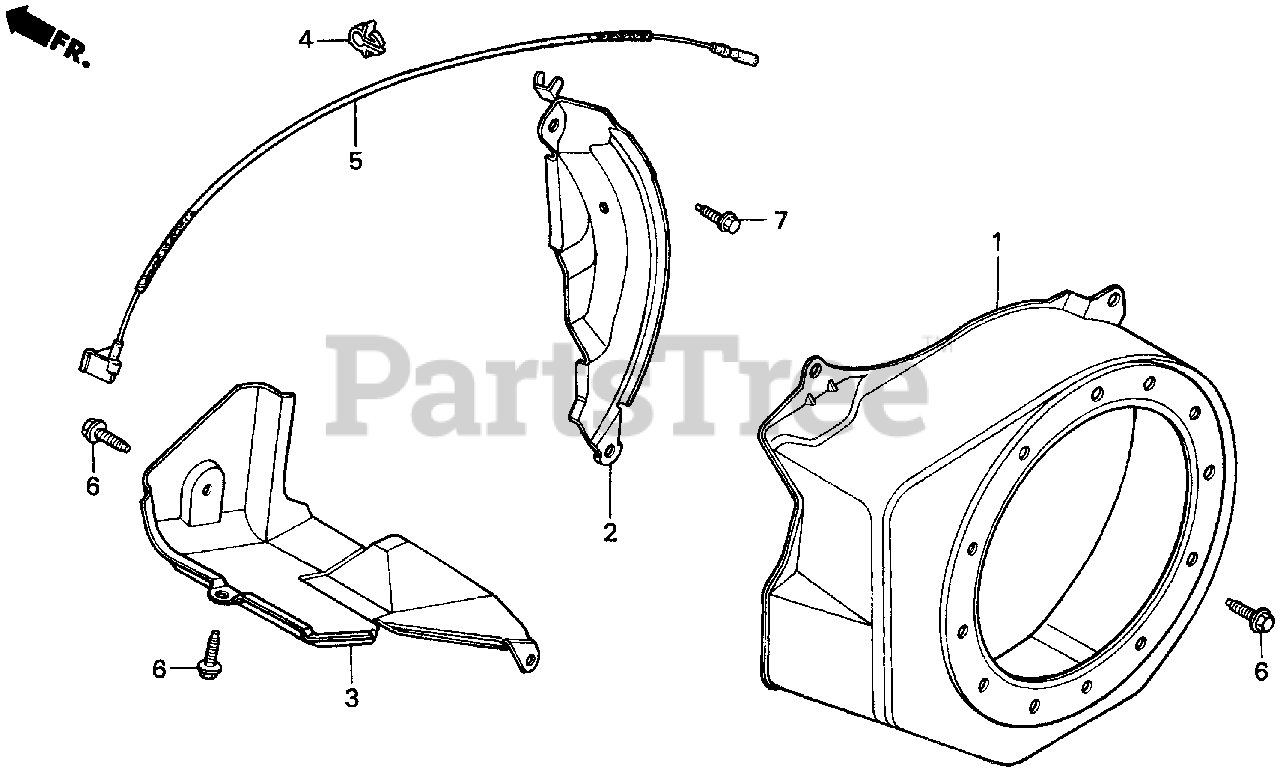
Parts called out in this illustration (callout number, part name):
1	COVER, FAN *R280* (POWER RED)
2	PLATE, SIDE (LAMP)
4	CLIP, IGNITION WIRE (8MM)
5	WIRE, STOP SWITCH (370MM)
6	BOLT, FLANGE (6X12) (CT200)
7	BOLT, FLANGE (6X20) (CT200)
